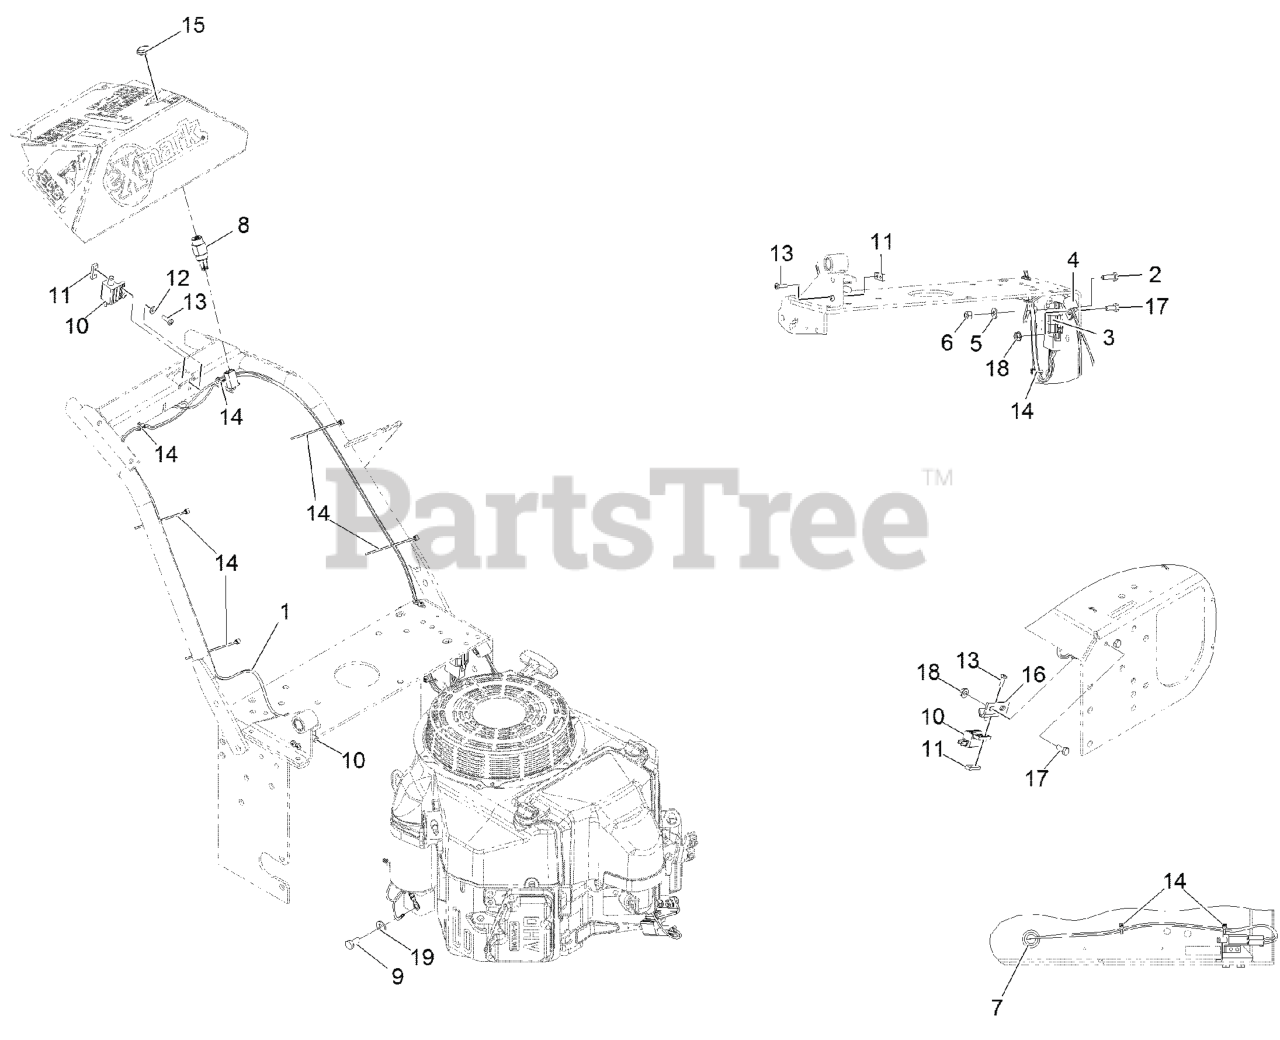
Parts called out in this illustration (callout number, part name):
1	HARNESS-WIRING
2	SCREW-HH
3	MODULE-INTERLOCK
4	CLIP-LOOM
5	WASHER-FLAT
6	NUT-LOCK, NI
7	GROMMET
8	SWITCH & KEY (INCLUDES NU
9	SCREW-HH
10	SWITCH-OPEN, NORMALLY
11	PLATE-TAPPED
12	WASHER-FLAT
13	SCREW-PPH
14	TIE-CABLE
15	NUT-SWITCH, IGNITION
16	BRACKET-SWITCH, BLADE
17	SCREW-HH
19	WASHER-PLAIN
